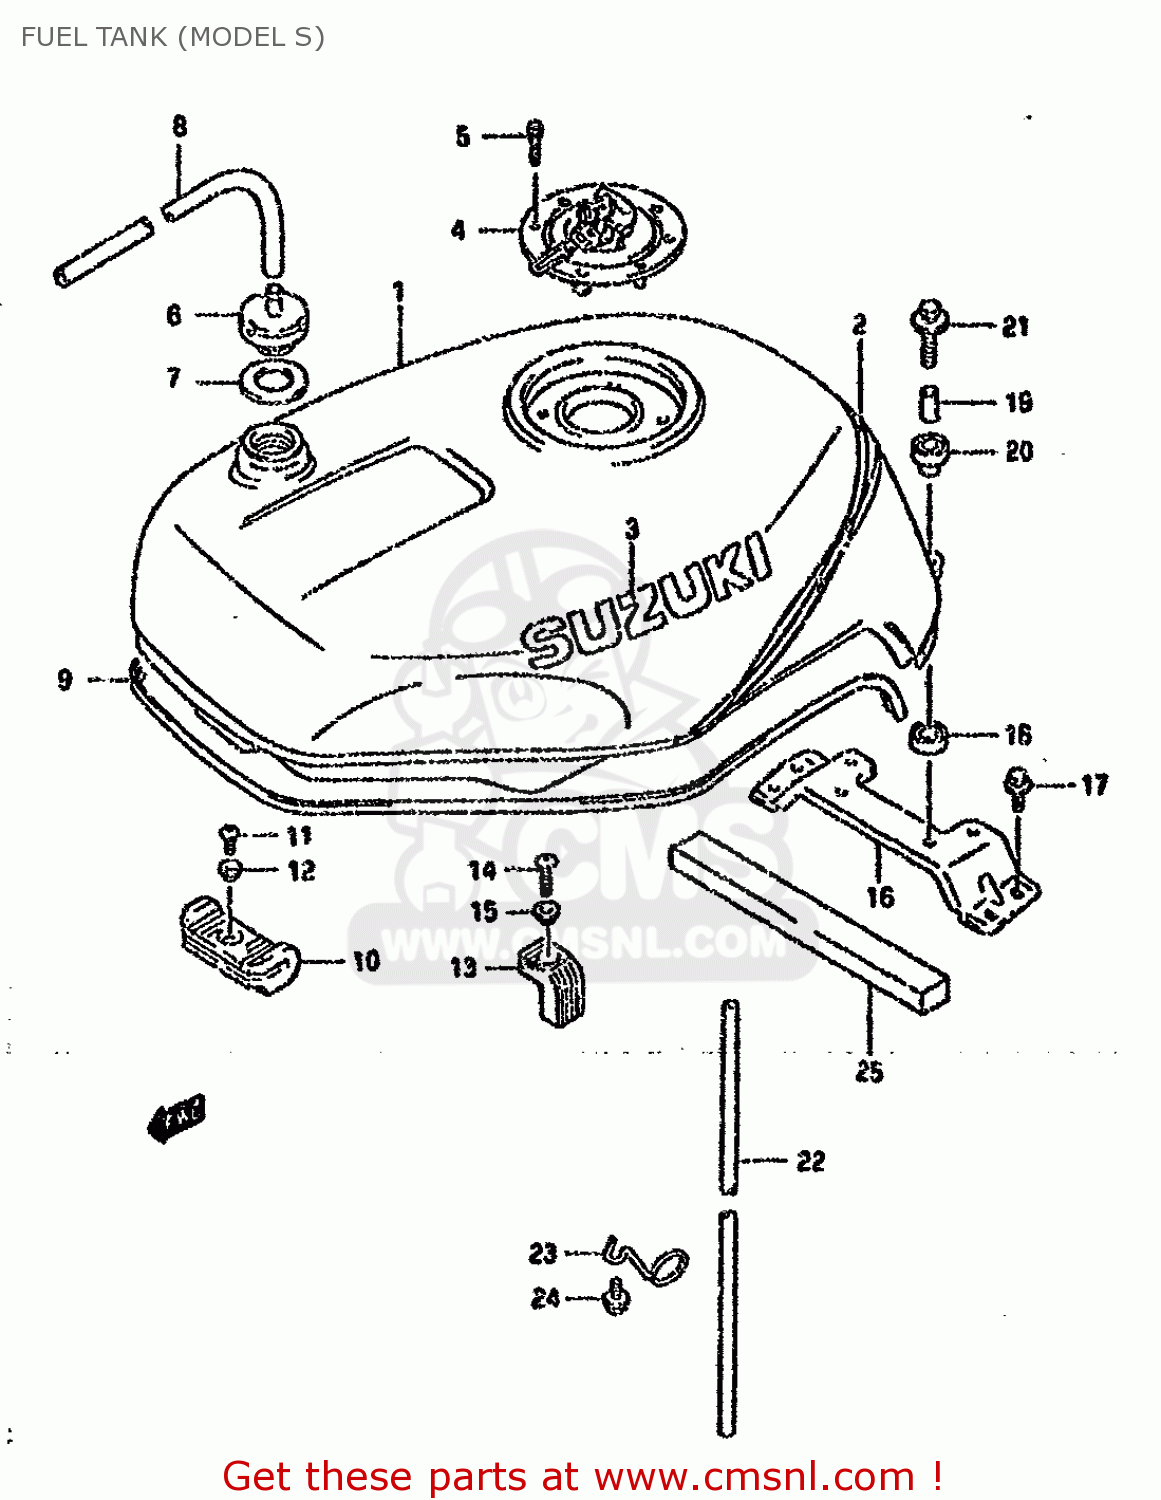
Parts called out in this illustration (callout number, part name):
1	TANK ASSY,FUEL
2	TAPE,FUEL TANK STRIPE
3	EMBLEM,FUEL TANK
4	CAP SET,FUEL TANK
5	BOLT(5X20)
6	PLUG,FUEL TANK BREATHER
7	GASKET(12.5X20X2.5) (NAS)
8	HOSE(5X8.2X600)
9	MOLDING,FUEL TANK
10	CUSHION,FUEL TANK FR
11	SCREW
12	WASHER
13	CUSHION,TANK SIDE
14	SCREW
15	WASHER
16	BRACKET,FUEL TANK,REAR
17	BOLT
18	CUSHION
19	SPACER
20	CUSHION
21	BOLT
22	HOSE(5X8.2X2000)
23	GUIDE,DRAIN HOSE
24	BOLT
25	CUSHION,AIR SEAL
29	BOLT
30	HOSE,WATER DRAIN (L:2000-670)
31	GUIDE,DRAIN HOSE
32	BOLT
33	CUSHION,AIR SEAL
